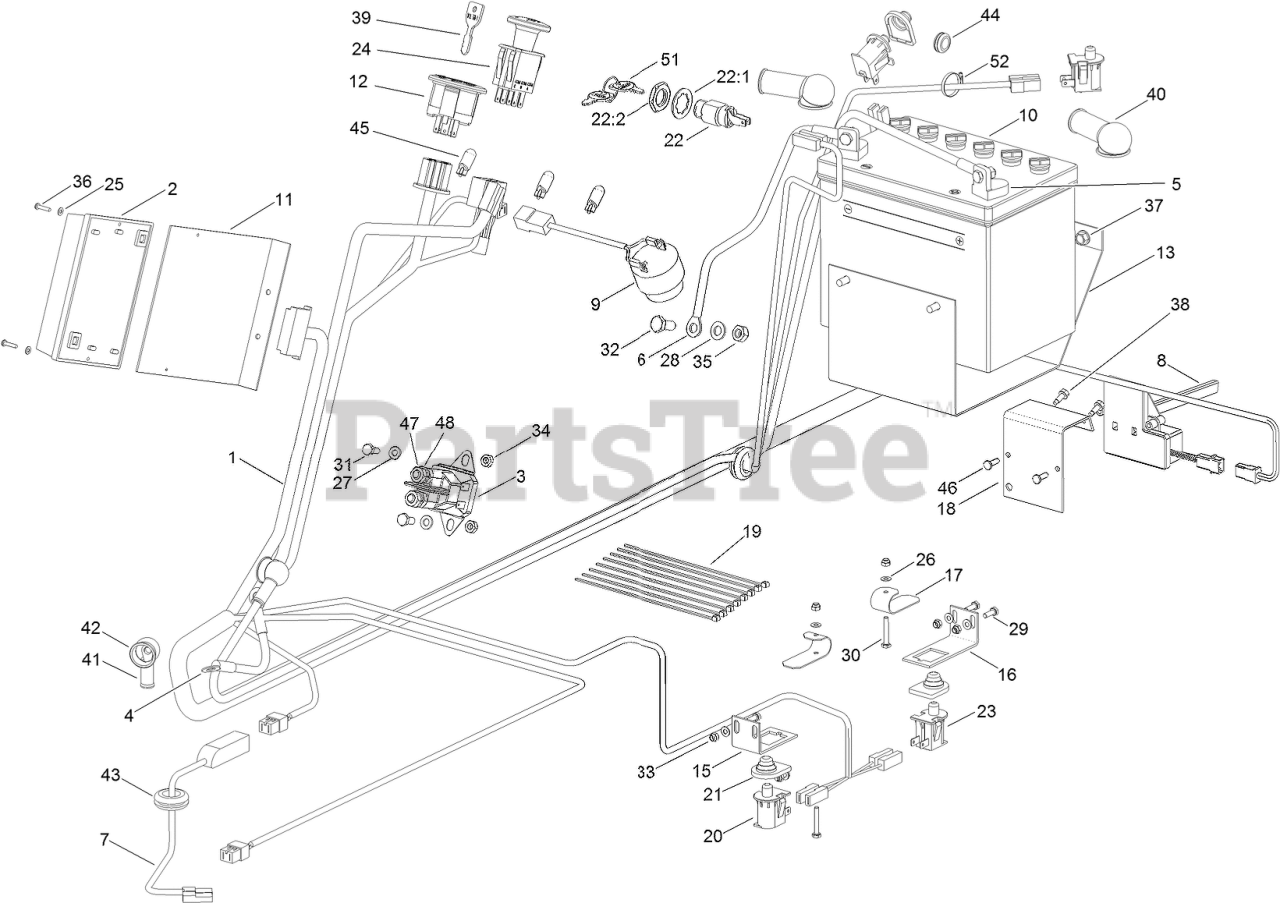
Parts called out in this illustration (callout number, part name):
1	HARNESS-WIRING
2	MODULE-CONTROL
3	SOLENOID
4	CABLE-STARTER
5	CABLE-BATTERY, POSITIVE
6	CABLE-BATTERY, NEGATIVE
7	HARNESS-CLUTCH
8	OVERLOAD SWITCH ASM
9	BUZZER
10	BATTERY-12V
11	HOLDER-MODULE
12	SWITCH-IGNITION
13	HOLDER-BATTERY
15	HOLDER
16	HOLDER
17	LEVER-SPRING
18	BRACKET-SWITCH
19	TIE-CABLE
20	SWITCH-DELTA
21	COVER-PROTECTIVE
22	STARTER SWITCH ASM
22:1	WASHER-TOOTH, INTERNAL
22:2	NUT-HH
23	SWITCH-DELTA
24	SWITCH-PTO
25	WASHER
26	WASHER
27	WASHER
28	WASHER-PLAIN
30	SCREW-HEX
31	SCREW-HH
32	SCREW-HH
33	NUT-HEX
34	NUT-LOCK
35	NUT-LOCK, NI
38	SCREW-TAP
39	KEY-IGNITION
40	BOOT-RUBBER
41	BOOT-RUBBER
42	NUT-HHF
43	BUSHING
44	BUSHING
46	Screw
47	NUT-HHF
48	WASHER-SPRING
51	KEY-IGNITION
52	CLIP-SNAP
